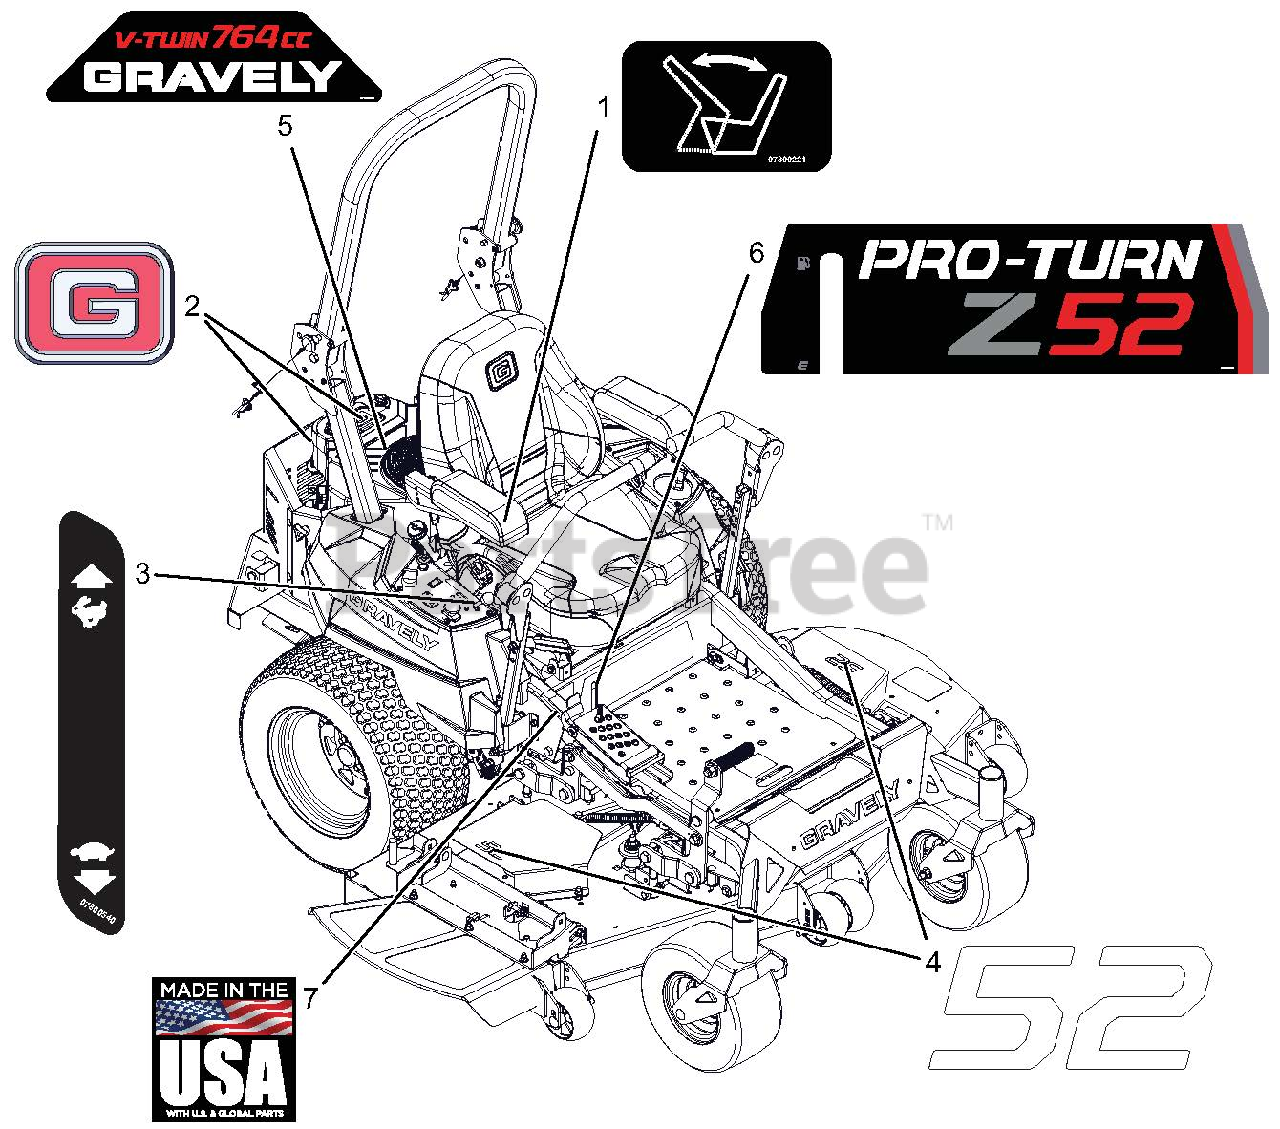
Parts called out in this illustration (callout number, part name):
1	DECAL - SEAT RELEASE
2	DECAL, GRAVELY BRAND
3	DECAL, DASH DECAL
4	DECAL, 52"
5	DECAL,ENGINE - GRAVELY 764CC
6	DECAL, PRO-TURN Z52
7	DECAL, MADE IN USA
